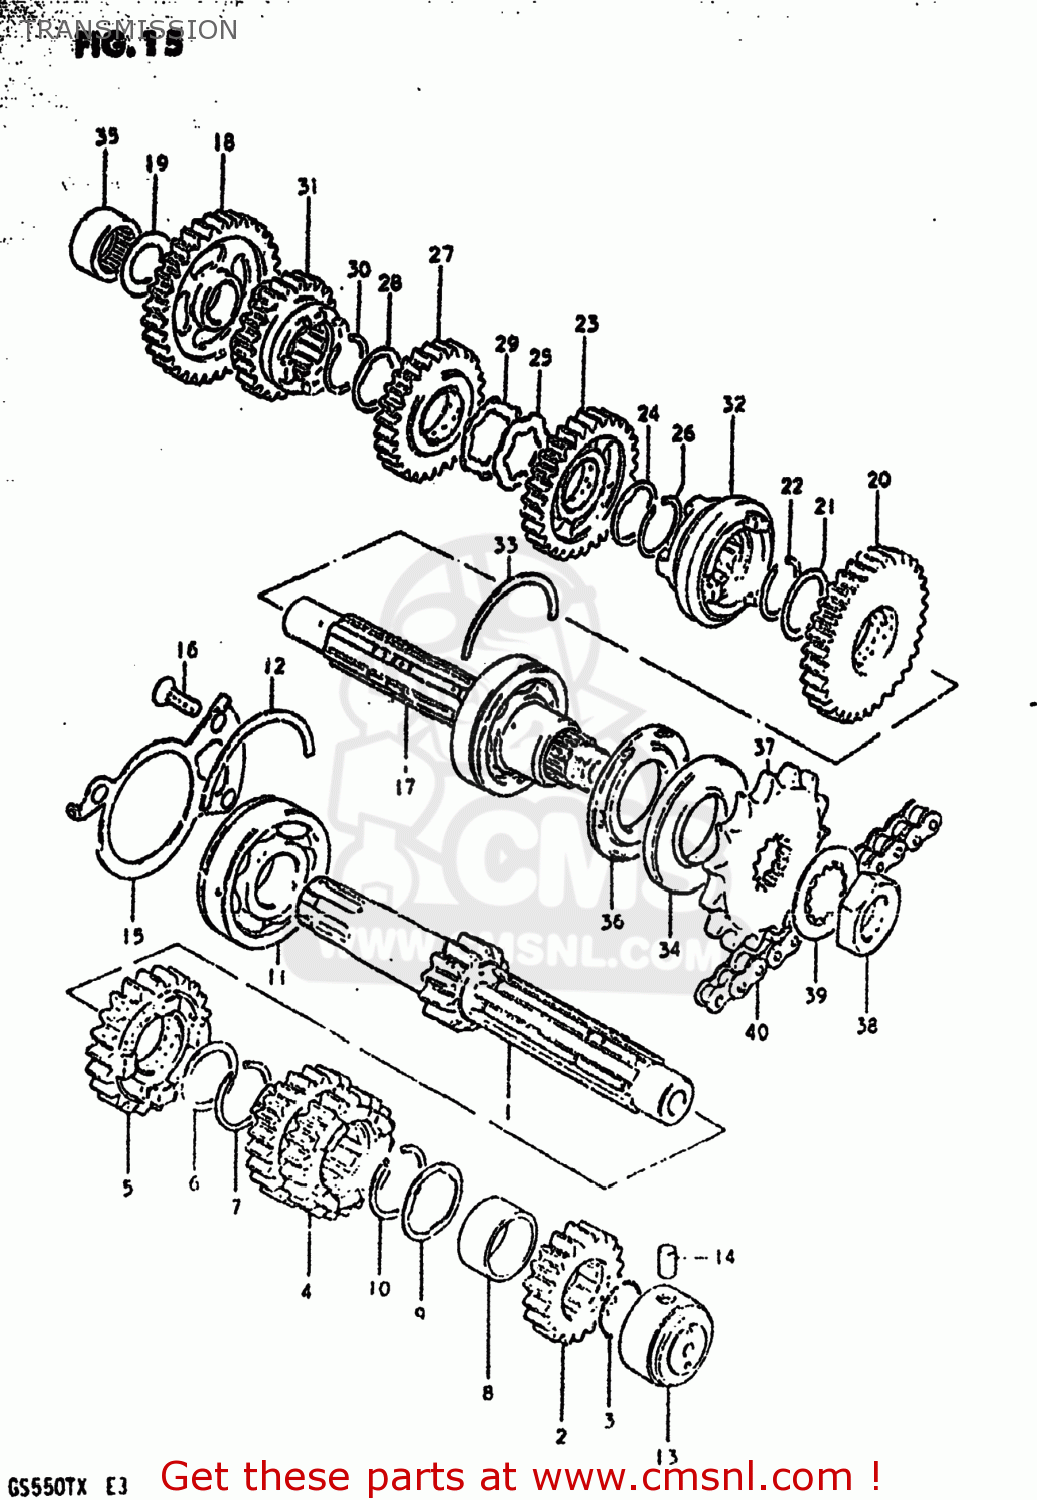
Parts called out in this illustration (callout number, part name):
1	SHAFT,COUNTER
2	GEAR,SECOND DRIVE
3	RING,SNAP
4	GEAR,THIRD DRIVE
5	GEAR,FIFTH DRIVE
6	WASHER
7	CIRCLIP
8	GEAR,SIXTH DRIVE
9	WASHER,LOCK
10	CIRCLIP
11	BEARING(25X62X17)
12	C-RING
13	BEARING
14	PIN
15	PLATE,COUNTERSHAFT BEARING
16	SCREW
17	SHAFT,DRIVE
18	GEAR,FIRST DRIVEN
19	WASHER
20	GEAR,SECOND DRIVEN
21	WASHER
22	CIRCLIP
23	GEAR,THIRD DRIVEN
24	WASHER,LOCK
25	WASHER,LOCK
26	CIRCLIP
27	GEAR,FOURTH DRIVEN
28	WASHER,LOCK
29	WASHER
30	CIRCLIP
31	GEAR,FIFTH DRIVEN
32	GEAR,SIXTH DRIVEN
33	C-RING
34	SEAL,OIL(32X62X7)
35	ROLLER BEARING (20X34X1
36	SEAL,OIL(32X62X5.5)
37	SPROCKET,ENGINE
38	NUT
39	WASHER
40	CHAIN ASSEMBLY,DRIVE
